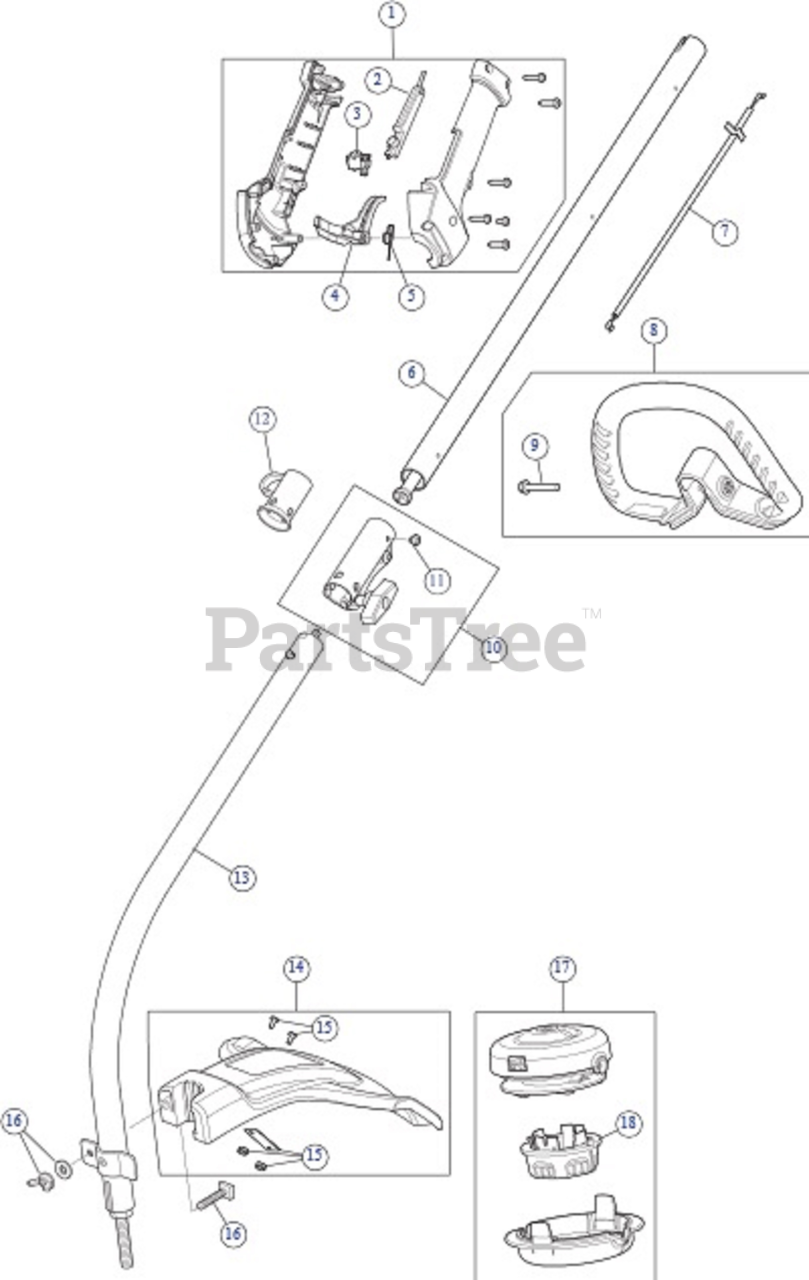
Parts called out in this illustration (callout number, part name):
1	Throttle Housing Assembly
2	Throttle Trigger Lock-Out
3	Trigger Switch Assembly
4	Throttle Trigger
5	Throttle Trigger Spring
6	Upper Drive Shaft Housing Assembly
7	Throttle Cable Assembly
8	D-Handle Assembly
10	Split Boom Coupler
11	Coupler Anti-Rotation Screw
13	Lower Drive Shaft Housing Assembly
14	Shield Assembly
15	Blade Assembly
16	Shield Mounting Hardware
17	Cutting Head Assembly
